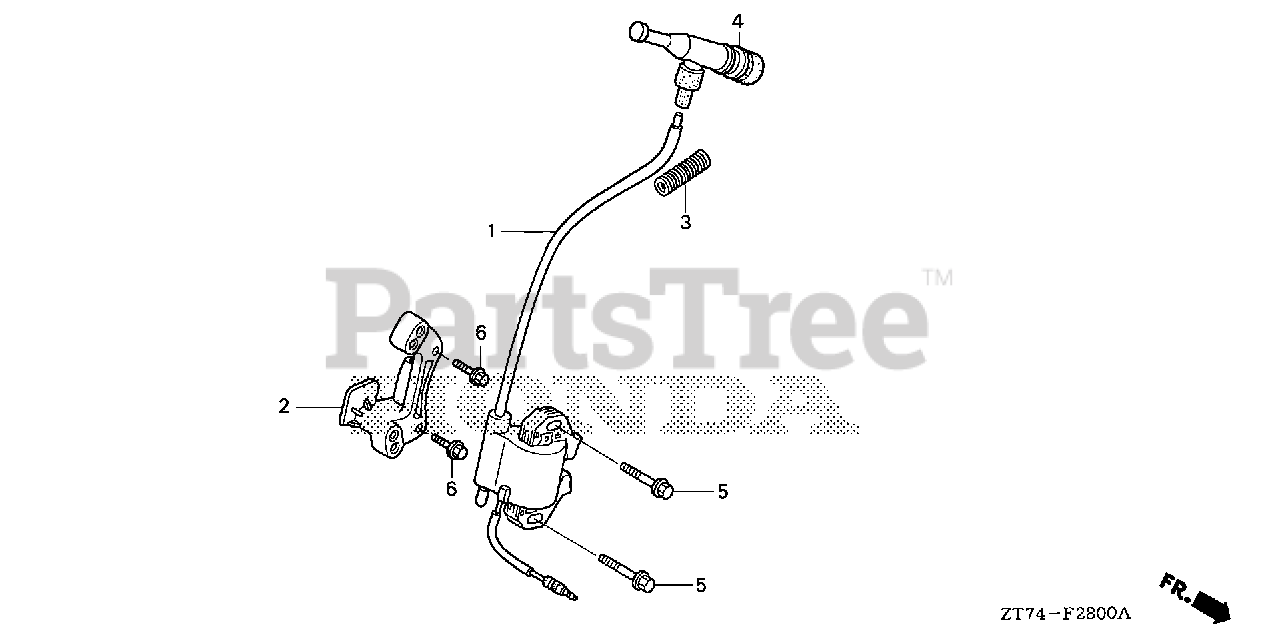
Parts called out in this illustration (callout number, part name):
1	COIL ASSY., IGNITION
2	BRACKET, IGNITION COIL
3	CORRUGATED TUBE (7X75)
4	CAP ASSY., NOISE SUPPRESSOR (NICHIWA Y-EZA)
5	BOLT, FLANGE (6X32) (CT200)
6	BOLT, FLANGE (6X20) (CT200)
